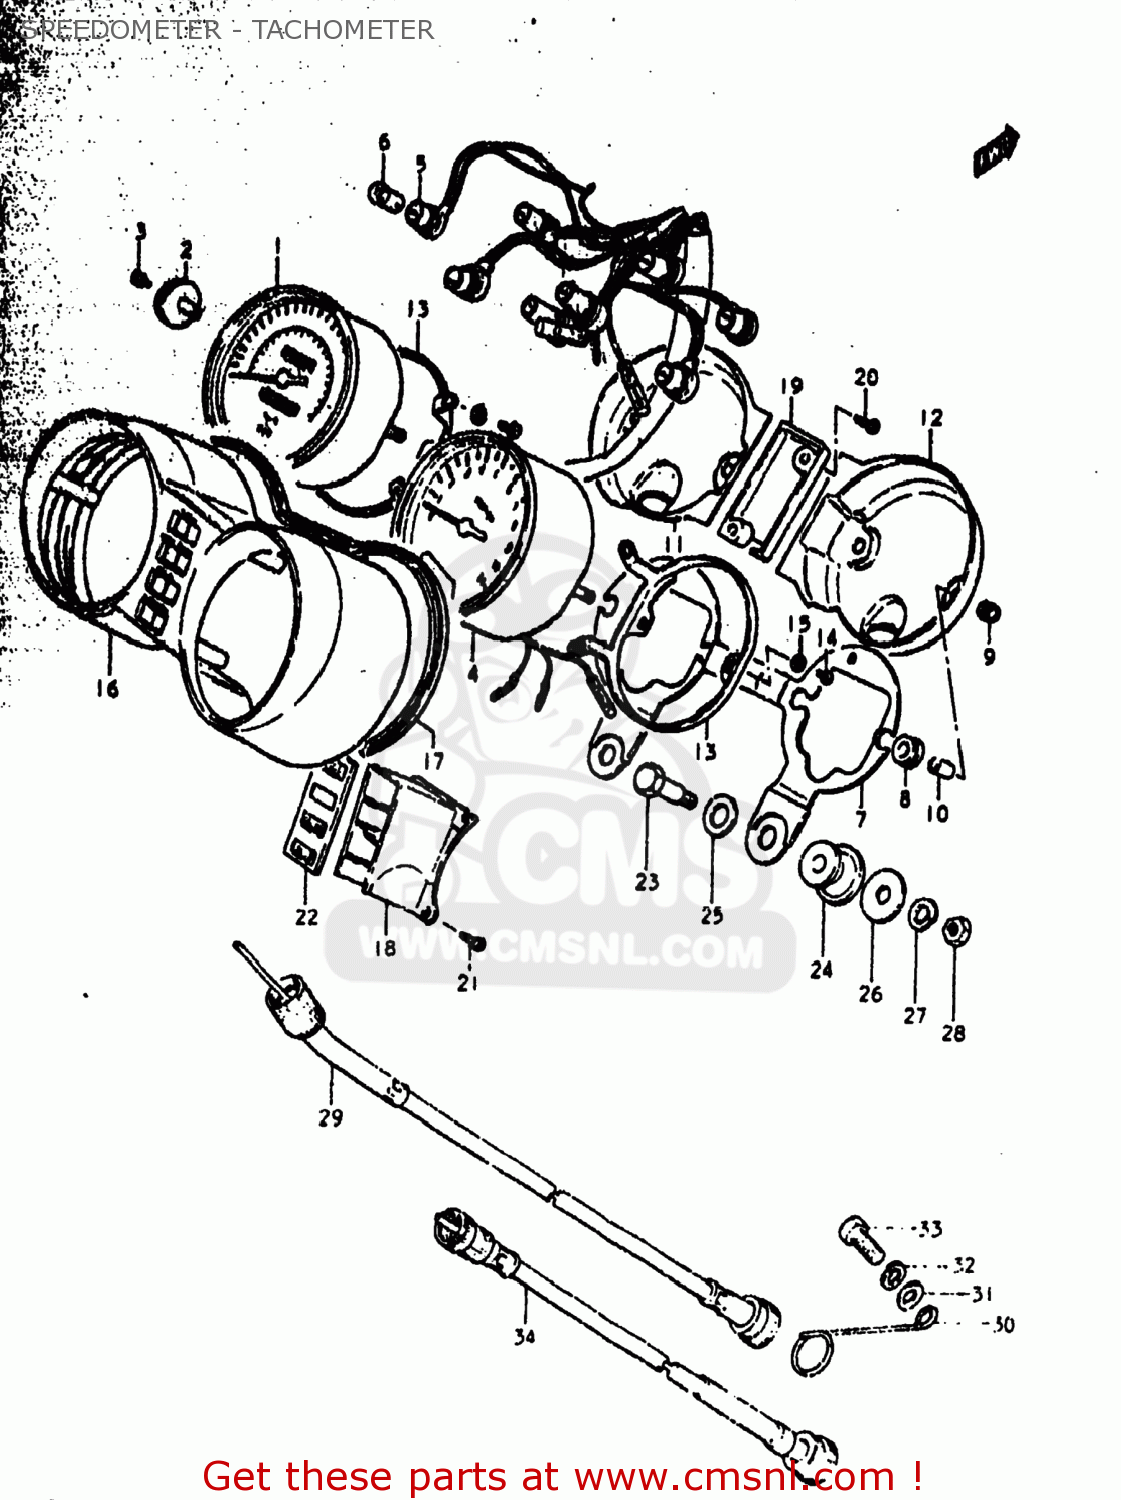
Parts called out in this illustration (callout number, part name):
0	SPEEDOMETER ASSEMBLY
1	SPEEDOMETER ASSEMBLY
2	KNOB,TRIP METER
3	SCREW
4	TACHOMETER
5	SOCKET,SPEEDOMETER
6	BULB(12V3.4W,STANLEY,A72A)
7	BRACKET,COMBINATION METER
8	CUSHION,SPEEDOMETER
9	NUT
10	SPACER,SPEEDOMETER
11	COVER,METER,UNDER
12	PLATE,TACHOMETER UNDER
13	HOLDER,METER
14	SCREW
15	LOCK WASHER
16	CASE,METER
17	CUSHION,METER CASE
18	CASE,PILOT BULB
19	PLATE,PILOT BULB CASE
20	SCREW,PILOT CASE
21	SCREW,SPEEDOMETER
22	LENS SET,PILOT LAMP
23	BOLT(8X31)
24	CUSHION,METER
25	WASHER
26	WASHER (8.5X29X1.6)
27	LOCK WASHER
28	NUT
29	CABLE ASSEMBLY,SPEEDOMETER
30	GUIDE,SPEEDOMETER CABLE
31	WASHER 6MM
32	LOCK WASHER
33	BOLT, UPPER
34	CABLE ASSEMBLY,TACHOMETER
